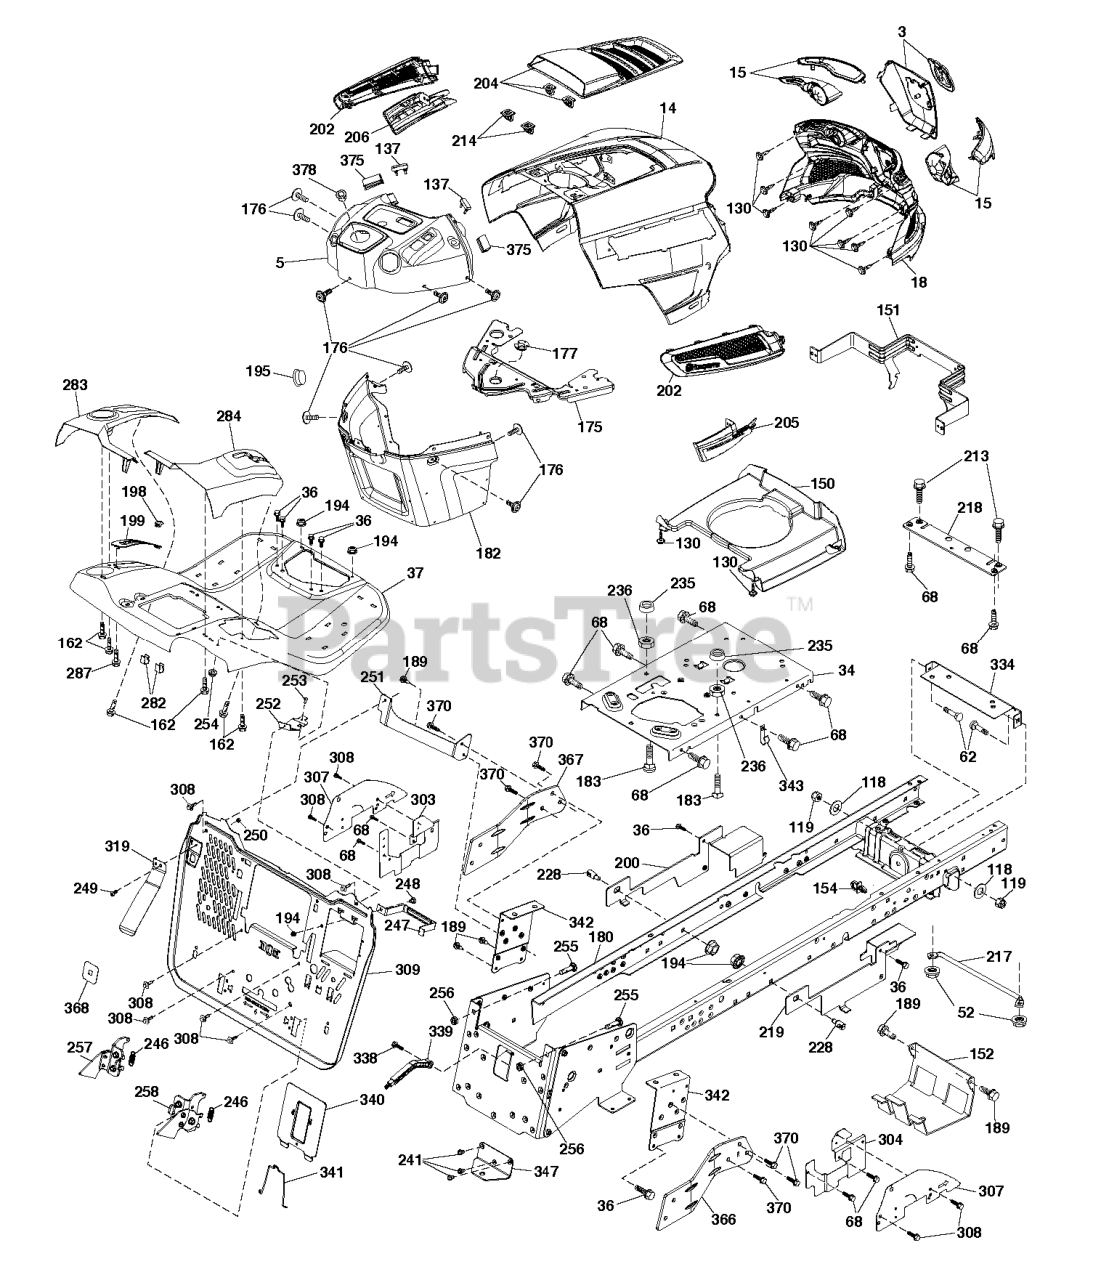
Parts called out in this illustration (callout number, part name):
5	DASHBOARD.UPPER.ASM.GT2.X498
5	DASH.ASM.W/BUMPERS.READYSTART
14	HOOD.ASM.HUSQVARNA.GT.TEX.ORAN
15	Service Kit
36	SCREW 5/16"
37	FENDER.TEX.SRD.CRD.BASE
118	WASHER PLAIN WASHER 3/8 X 0.08
118	WASHER
137	BUMPER DASH
150	AIR.DUCT.GTV.BLACK
151	BRACKET.PIVOT.HOOD.GT.HUSQ.II
152	SHIELD.BROWNING.W/TEX
154	PUSH CLIP
175	PLATE.PNT.CROSSMEMBER.HUSQ/PRE
176	SCREW.#10-24X5/8.RN.QU
177	BUSHING STEERING
180	CHASSIS WELDMENT.CRD2.BKP_BLTS
182	DASH LOWER.HUSQ.PRED NO CRUISE
189	SCREW
195	PLUG.HOLE.DASH.LOWER.12V.BLK
198	INDICATOR.DECK.LIFT.RED
199	PLATE DECK LIFT
200	SHIELD.LH.CHASSIS.MS431
202	Vents
205	SIDE.TRIM.RH.GT.HUSQ.II
206	SIDE.TRIM.LH.GT.HUSQ.II.GRAY
213	SCREW HEXAGON HEAD SCREW 5/16-
214	CLIP.RETAINER.TINNER.
217	ROD.PIVOT.HOOD
218	X-PIECE.HOOD.STOP.NON/
219	SHIELD.RH.CHASSIS.MS431
228	STUD.FASTNER.W/ANTI-ROTATE
228	STUD.W/"D"ANTI-ROTATION
236	NUT.CENTERLOCK.5/16-
246	SPRING.LTCH.BGR.GEN2.5.CRD.TEX
247	STRAP.BATTERY.TCRD.GEN2.5X431
248	BOLT.CARR.5/16-18X1/2
249	SCREW.BUTTONHD.10-24X1/2.(2 2)
251	BRACKET.PNT.LH.SUPP.BKPLT.EDIP
252	BRACKET.PNT.RH.SUPP.BKPLT.EDIP
253	BOLT CUP HEAD SQUARE NECK BOLT
254	NUT T
257	LATCH.ASM.BGR.LH.GEN2.5.STMPD
258	LATCH.ASM.BGR.RH.GEN2.5.STMPD
282	CLIP.RETAINER.CONSOLE.LT.HUSQ
283	CONSOLE.DECKLIFT.CRDII.498
284	CONSOLE.PEDAL.HYDRO
287	SCREW 1/4X20
303	Shields
304	Shields
307	SHIELD.UPPER.CRD.SRD.ISO
308	BOLT.5/16-18UNCX3/4 W/SEMS.BLK
309	BACKPLATE.TEXCRD2.5.BAGGER.479
319	LEVER.PRSNC.BGR.TEX.CRD.GEN2.1
334	BRACKET.ENGINE
339	LEVER LEVER BAGGER
340	BATTERY.DOOR.TCRD.GEN2.5.MS479
341	LATCH.BATTERY.DOOR.TCRD
342	SUPPORT.PNT.FENDER.CRD.TEX
343	CLIP CLIP
347	HITCH HITCH TOW TEX CRD GEN 2
366	Brackets
366	BRACKET.RH.FRONT.BAGGER.BLACK
367	BRACKET.LH.FRONT.BAGGER.BLACK
367	Brackets
368	FULL.LEVER.BAGGER.TEX.CRD
370	SCREW 3/8-16X1
375	BUMPER CLIP-ON. DASH 1"
378	BUSHING FLANGE; PLASTIC
